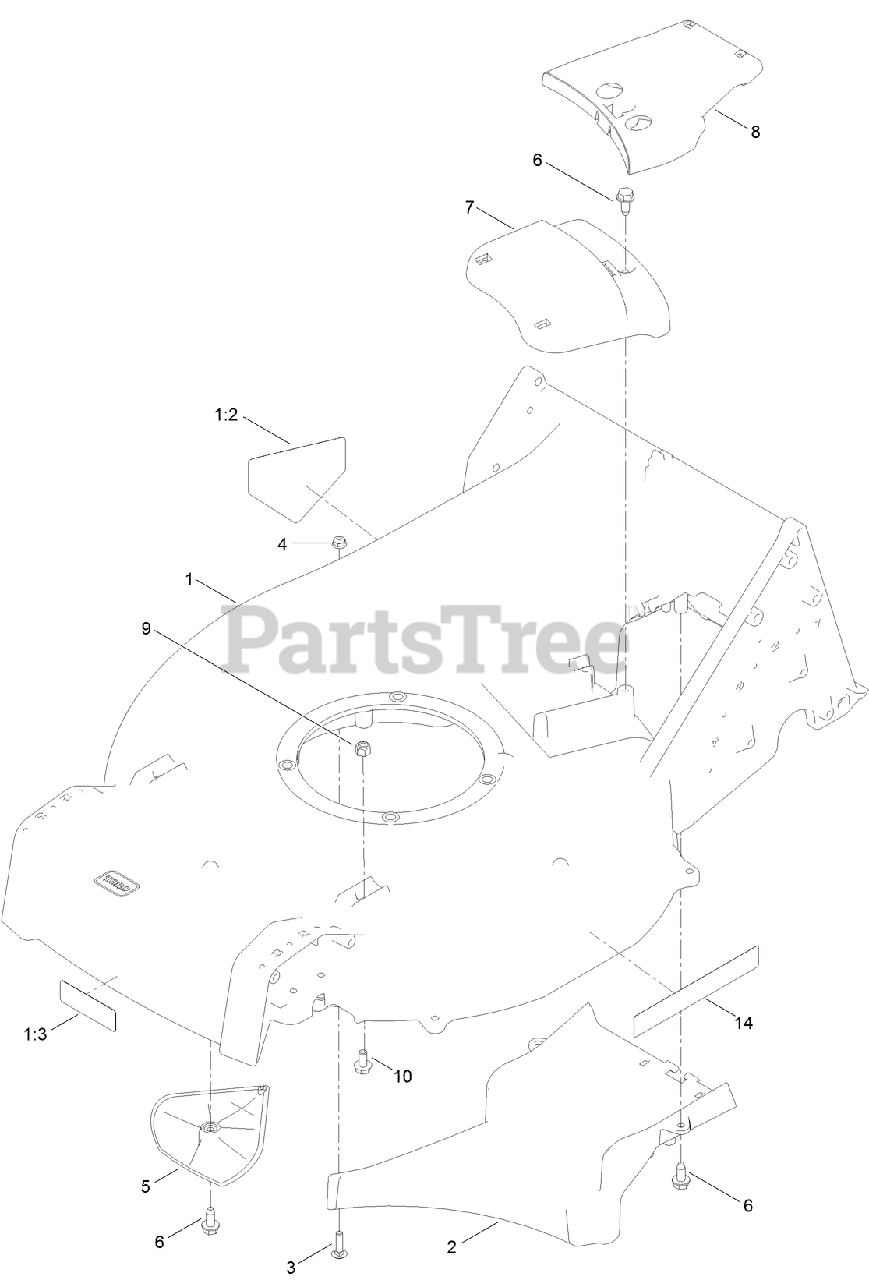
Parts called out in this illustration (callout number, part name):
1	HOUSING ASM
1:2	DECAL-DANGER
1:3	DECAL-WARNING, BLADE
2	FLOOR-CHUTE
3	SCREW-CARR
4	NUT-HF
5	KICKER
6	SCREW-HWHTF
7	COVER-BELT, FRONT
8	COVER-BELT, REAR
9	NUT-LOCK, NI
10	SCREW-HHF
14	DECAL-RECYCLER
